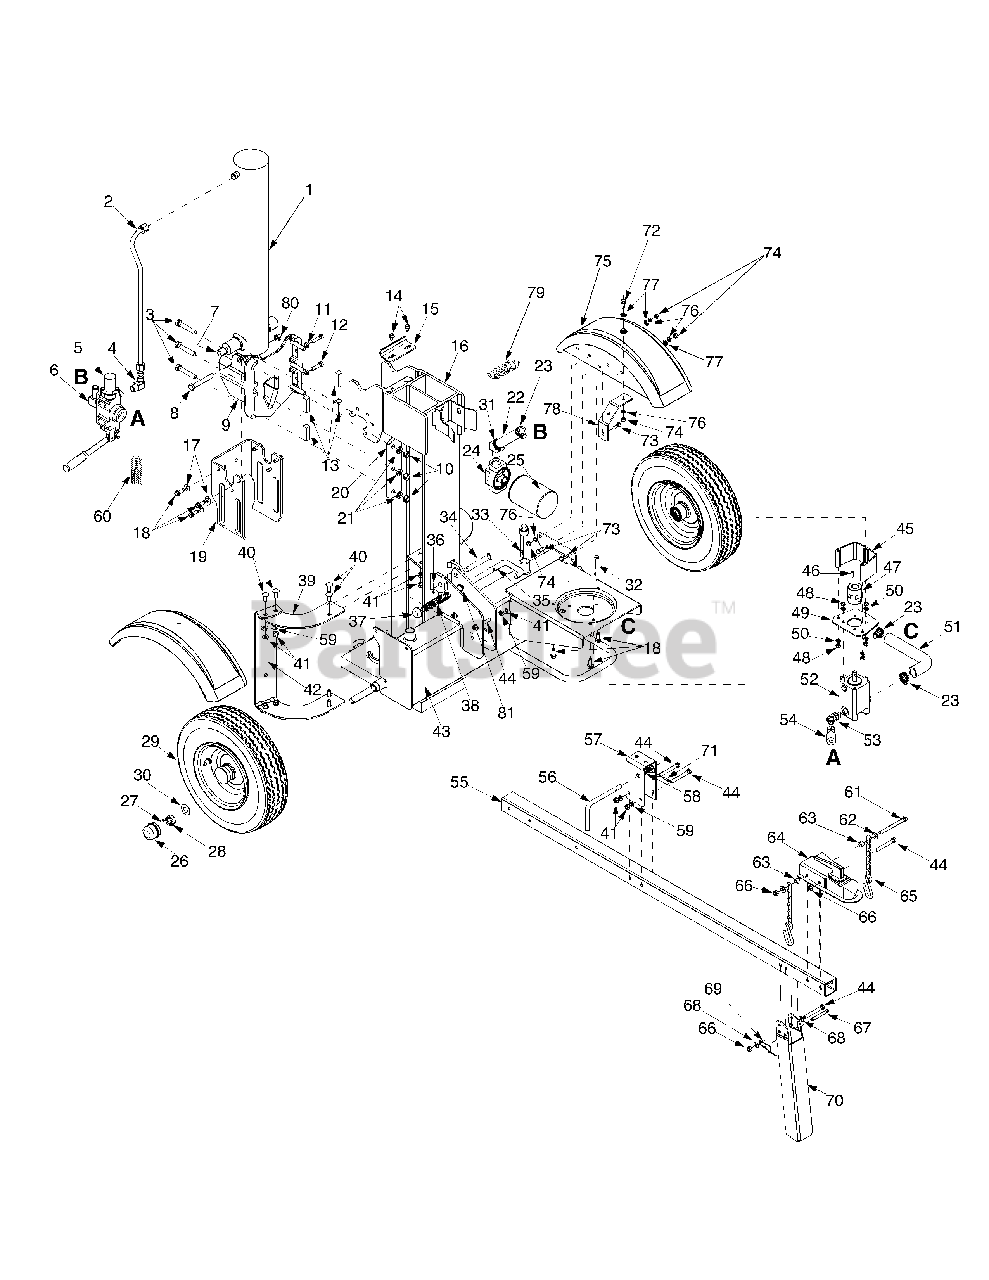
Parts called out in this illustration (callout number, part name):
1	Hydraulic Cylinder 718-0769A
1	Kit Seal 4.5" for XINGHUI cylinder 718-0769A
1	Kit Seal 4.5" for ENERGY cylinder 718-0769A
2	Hydraulic Tube
3	Hex Cap Screw 1/2-20 x 2.75
4	90 Degree Solid Adapter
5	Control Valve
6	Return Elbow
7	Nipple Pipe 1/2-14
8	Hex Cap Screw 1/2-13 x 3.25
9	Wedge Assembly
10	Hex Lock Nut, 1/2-20
11	Hex Jam Nut 3/8-24
12	Hex Cap Screw 3/8-24 x 1.5
13	Adjustable Gib
14	Flat Washer.635 x.93 x.06
15	Hex Lock Nut 1/2-13
17	Hex Screw, 5/16-18 x 3.25
18	Hex Washer Screw 3/8-16 x 1.0
19	Dislodger Bracket
20	Back Plate
22	Return Hose 3/4" ID x 44" Lg.
23	Hose Clamp 5/8"
24	Filter Housing
25	Oil Filter
28	Slotted Nut 3/4-16
29	Wheel Assembly
29	Cone Bearing
29	Grease Retainer
30	Flat Washer.760 ID x.500 OD
31	Adapter 3/4-14
32	Hose Guard
33	Vented Dipstick
36	Cotter Pin
38	Compression Spring
39	Log Tray Bracket
40	TT Screw, 5/16-18 x.875
41	Flange Lock Nut, 3/8-16
44	Hex Bolt 3/8-16 x 3"
45	Coupling Shield
46	Square Key 3/16" x.75
47	Flexible Coupling
48	Flange Lock Nut, 5/16-18
49	Rear Coupling Support Bracket
50	Fender Mounting Bracket
53	45 Degree Elbow Fitting
54	High Pressure Hydraulic Hose
55	Tongue Assembly
58	Compression Spring
60	Hose Guard
61	Hex Cap Screw, 3/8-16 x 3.50
62	Flat Washer,.375 x.738 x.063
63	Hydraulic Valve Control
64	Hitch Coupling Assembly
66	Fender (Black)
70	Jack Stand
71	Spiral Pin
72	TT Screw, 5/16-18 x 0.875"
73	TT Screw, 5/16-18 x 1.00
74	Light Kit
75	Light Bracket - LH
75	Light Bracket - RH
76	Screw, 5/16-18 x 1.25
77	Jam Nut, 3/8-16
78	Speed Nut, .3125 ID
80	Valve Handle Link
81	Cotter Pin
82	Hex Screw, 5/16-18 x 1.00
